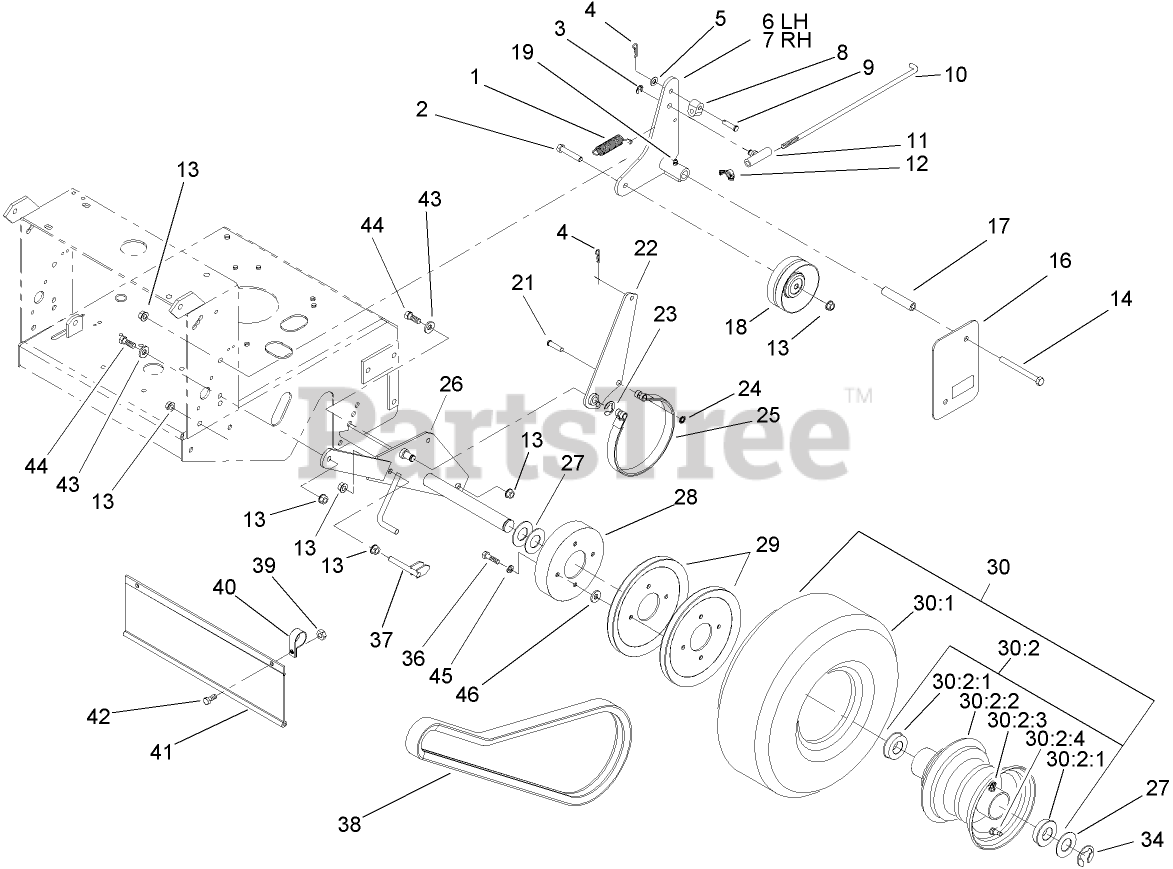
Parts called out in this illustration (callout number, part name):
1	SPRING-EXTENSION
2	SCREW-HH
3	RING-RETAINING
4	PIN-COTTER
5	WASHER-PLAIN
6	RH IDLER ARM ASM
7	LH IDLER ARM ASM
8	FITTING-ROD
9	PIN-CLEVIS
10	ROD-BRAKE
11	SWIVEL-BRAKE
12	WINGNUT-NYLOCK
13	NUT-HHF, WHIZ
14	SCREW-HH
16	SHIELD-WHEEL, DRIVE
17	SPACER-SHIELD
18	IDLER-DRIVE, WHEEL
19	FITTING-GREASE
21	PIN-CLEVIS
22	ARM-BRAKE
23	RING-RETAINING, EXTERNAL
24	NUT-PUSH
25	BAND-BRAKE
26	AXLE ASM
27	WASHER-SPACER
28	DRUM-BRAKE
29	SHEAVE-WHEEL, DRIVE
30	WHEEL AND TIRE ASM
30:2	WHEEL AND HUB ASM
30:2:1	BEARING-FLANGED
30:2:2	Rim ASM
30:2:3	Fitting-Grease
30:2:4	Valve Stem and Cap
34	RING-SNAP
36	SCREW-HH
37	Scraper
38	BELT-DRIVE, WHEEL
39	NUT-LOCK, NI
40	CLAMP-R
41	SHIELD-TRAILING
42	SCREW-HH
43	WASHER-BELLEVILLE
44	SCREW-HH
45	WASHER
46	WASHER-LOCK
